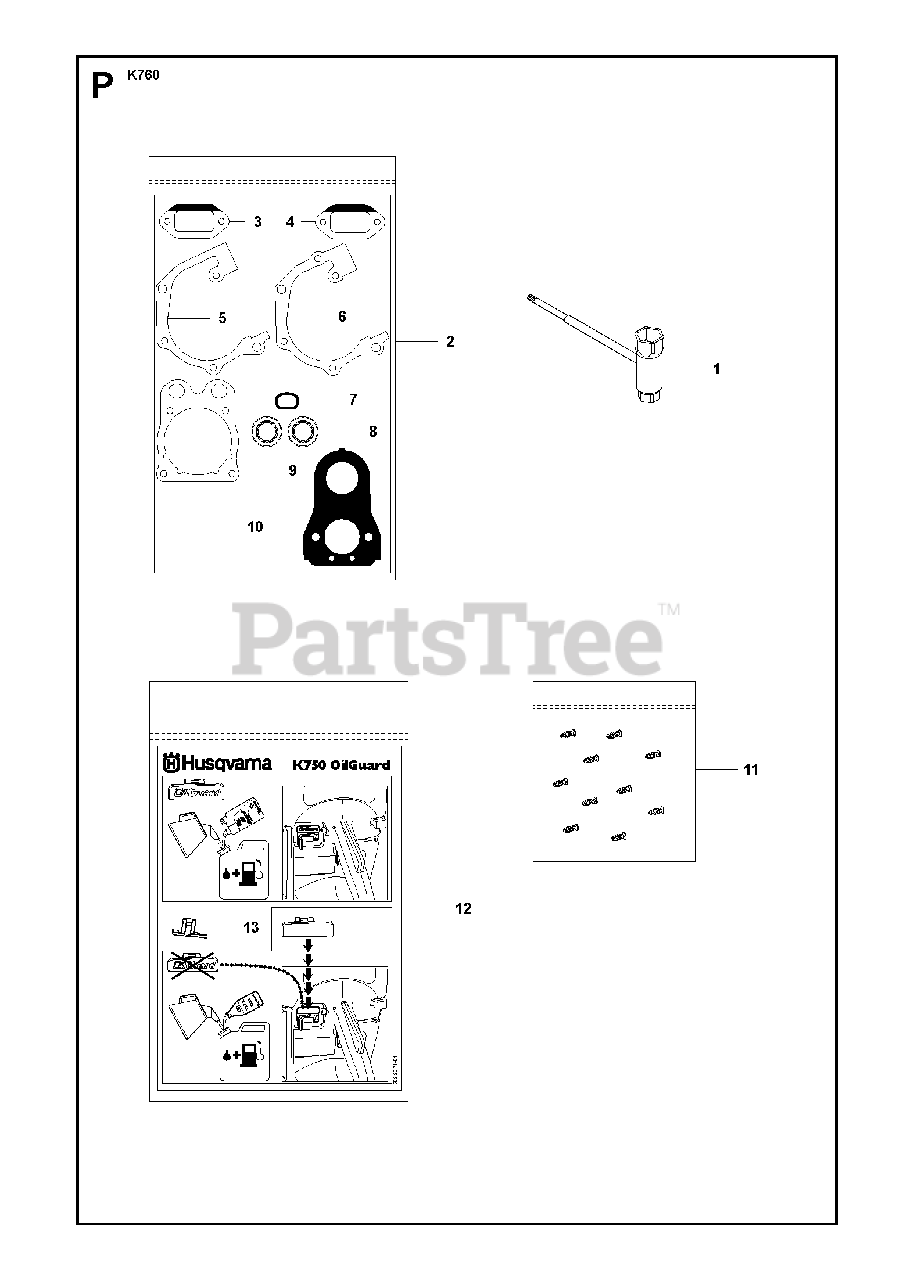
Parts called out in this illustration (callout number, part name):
2	GASKET KITIncl. 3 - 10
4	GASKET
8	SEALING RING
10	GASKET
11	KITIncl. 10 Pins
12	KIT
